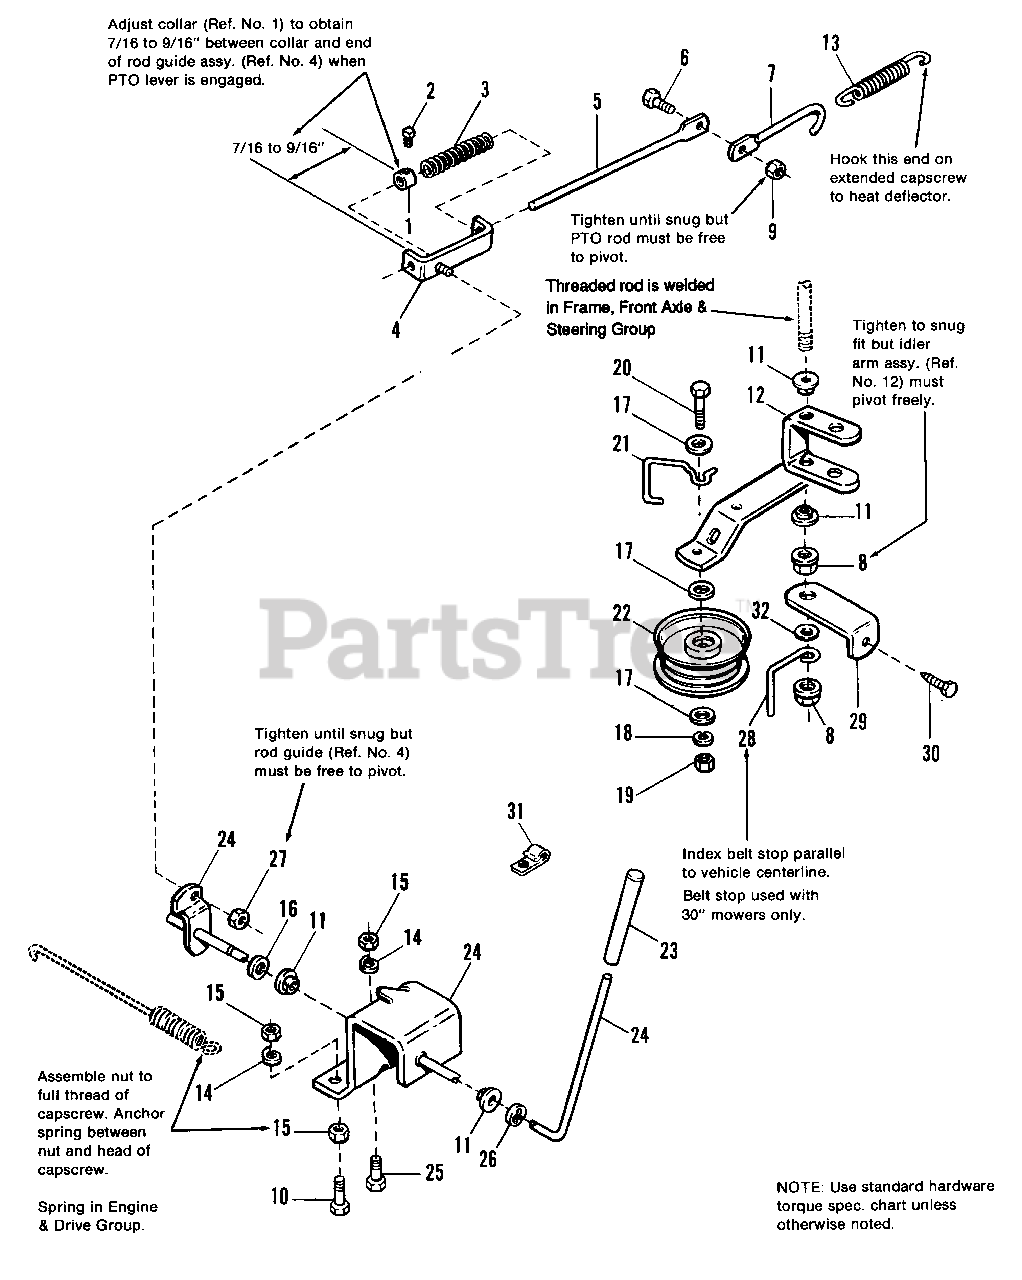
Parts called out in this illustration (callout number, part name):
1	COLLAR, Set
2	SETSCREW, 1/4-20 x 3/8
4	ROD GUIDE ASSY.
5	ROD, P.T.O., Front
6	CAPSCREW, Hex Hd., 1/4-20 x 5/8
7	ROD, P.T.O., Rear
8	LOCKNUT, Flange, 1/2-13
9	LOCKNUT, Hex, Lock, 1/4-20
10	CAPSCREW, Hex Hd., 5/16-18 x 1-1/2
12	P.T.O. IDLER ARM ASSY.
13	SPRING, Return
14	LOCKWASHER, 5/16
15	NUT, Hex, Full, 5/16-18
16	WASHER, Plain
17	WASHER, Plain, 13/32
18	LOCKWASHER, 3/8
19	NUT, Hex, 3/8-16
20	CAPSCREW, Hex Hd., 3/8-16 x 1-1/2
22	PULLEY, Idler
24	P.T.O. LEVER ASSY. (Incl. Ref. No. 16)
25	CAPSCREW, Hex Hd., 5/16-18 x 5/8
26	RING, Retaining
27	LOCKNUT, Hex, 5/16-18
28	STOP, Belt (Used on Mfg. Nos. 1691106, 1691535, 1691551 only)
29	SUPPORT, P.T.O.
30	SCREW, Taptite, 5/16-18 x 1/2
31	CLAMP, Wire
32	WASHER, 5/16 (Used on Mfg. Nos. 1691106, 1691353, 1691551 only)
